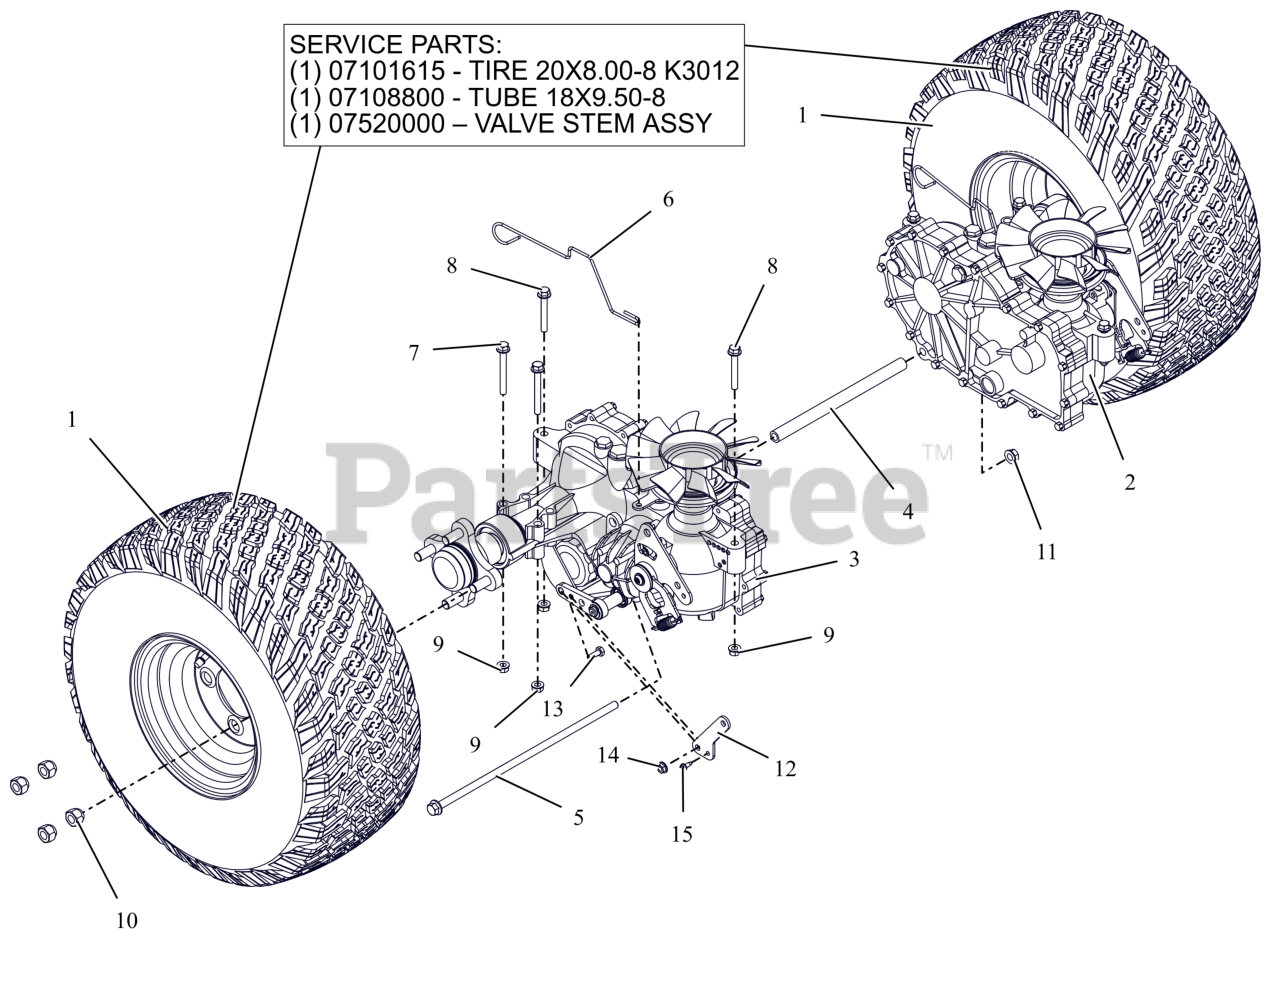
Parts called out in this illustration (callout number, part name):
1	ASM-WHL/TIRE 20X8.00-10 TURF
2	TRANSAXLE- 2800 - LH
3	TRANSAXLE- 2800 - RH
4	SPCR, TRANSAXLE .406 ID X .630 OD X 9.27 (BLACK)
5	BLT, HEX-FLG 0.375-16X13 GR5 ZC120
6	WIRE- DUMP VALVE LEVER
7	BLT,HEX-FLG .31-18X2.75 G5 ZCC
8	BLT,HEX-FLG .31-18X2.25 G5 ZCC
9	NUT,LK-CTR-FLG .31-18 GF ZCC
10	NUT, WHEEL .50-20 ZCC
11	NUT-LK-CTR-FLG .375-16 GF ZCC
12	PLATE- ADAPTOR PARKING BRAKE
13	BLT, HEX .25-20X.75 G5 ZCC
14	NUT-LK-CTR-FLG .25-20 ZC120
15	SCR,TAP #10-24X.50 HWH TR ZCC
